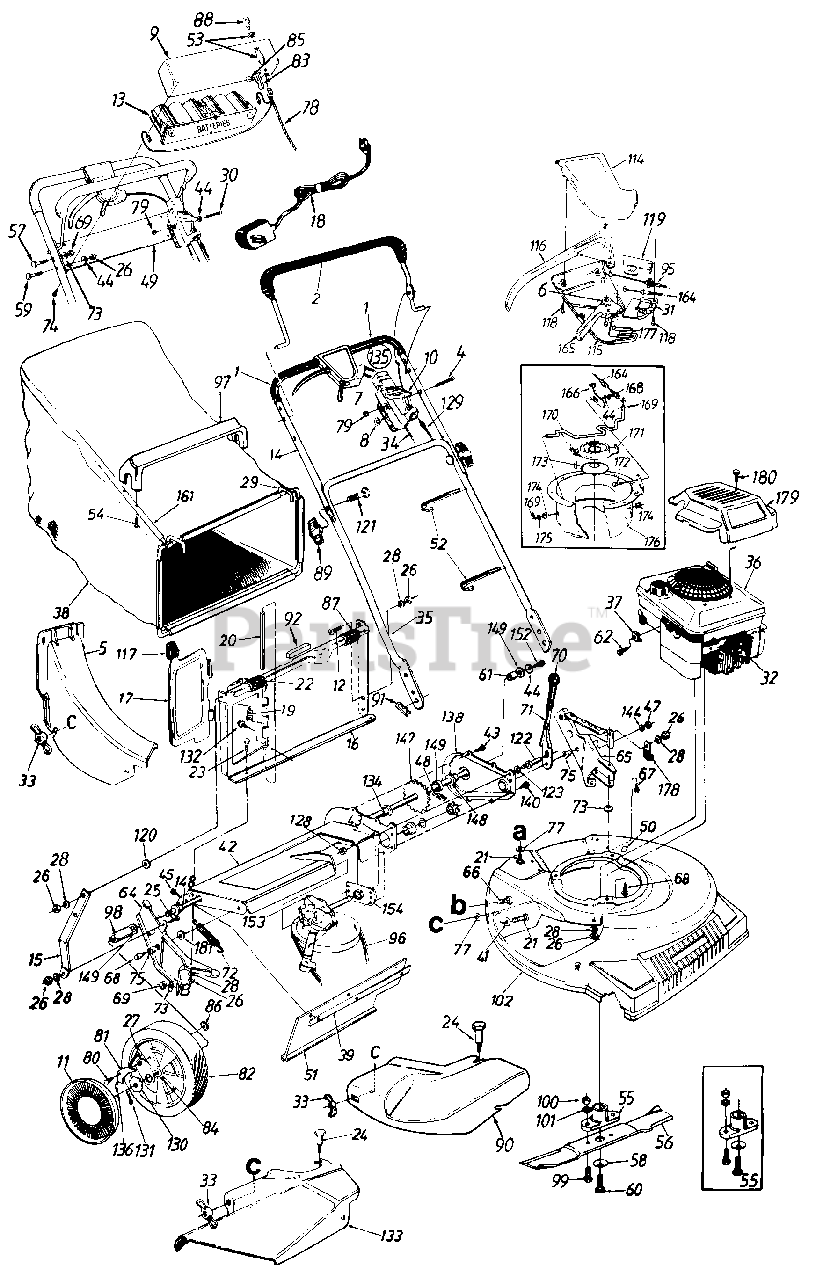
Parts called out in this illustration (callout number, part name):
1	Grip (2 Req'd.)
2	Control Handle
4	Oval C-Sunk Scr.
5	Rear Discharge Chute Ass'y.
6	3 Tooth Rack Gear Insert
7	Throttle Body
8	Spr. Wash. .66" I.D.
9	Battery Tray
10	Throttle Lever
11	Hub Cap (Beige)
12	Truss Mach. Scr. 1/4-20 x .62" Lg.
13	Battery Pack-12 Volt
18	Battery Charger
19	Torsion Spring
20	Pivot Pin
21	Carriage Bolt 1/4-20 x .62"
22	Truss Mach. Scr. 1/4-20 x .75" Lg.
23	Hex Bolt 1/4-20 x .5" Lg.
24	Shoulder Bolt Special
25	Hex Bolt 1/4-20 x .62" Lg.
26	Hex Nut 1/4-20 Thd.
27	Pawl Plate
28	L-Wash. 1/4" I.D.
30	Hex Bolt 1/4-20 x 2" Lg.
31	S.P. Control Cover
32	Spark Plug Insulator
33	Wing Nut
34	Throttle Cable 61"
36	Engine
37	Casing Clamp
38	Grass Bag
39	Retaining Strip
41	Fl-Wash. .344" I.D. x .62"
44	Bell-Wash. 1/4" I.D.
45	Hex AB-Tap Scr. 1/4 x .62"
47	Hex Patch L-Nut 3/8-24 Thd.
48	#48 Chain .500" Pitch x 30 Links
51	Rear Flap 3.75" x 17.30" Lg.
52	Cable Tie
53	Ignition Switch
54	Hex AB-Tap Scr. #12 x 1.25" Lg.
55	Blade Adapter Kit
56	21" Mulching Blade
57	Curved Carr. Bolt 5/16-18 x 1.38" Lg.
58	Bell-Wash. .46" I.D.
59	Carr. Bolt 1/4-20 x 1.25" Lg.
60	Hex Bolt 7/16-20 x 1.5"
61	Spacer.513" I.D.
62	Hex Wash. Hd. Scr. #10-32 x .62" Lg.
64	R.H. Handle Wheel Brkt. Ass'y.
65	L.H. Handle Wheel Brkt. Ass'y.
66	Carriage Bolt 5/16-18 x .62"
67	Hex B-Tap Scr. 5/16-18
68	Hex TT-Tap Scr. 3/8-16
69	Hex Nut 5/16-18 Thd.
71	Height Adj. Lever
72	Extension Spring 3.80" Lg.
73	Bell-Wash. 5/16" I.D.
74	Truss Mach. Tap Scr. 1" Lg.
75	Shld. Spacer .5" Dia.
77	Bolt Retainer 1/4 x .50" O.D.
78	Wire Harness
79	Hex L-Nut 1/4-20 Thd.
80	Shld. Scr. .342" Dia. x .268
81	Pawl
82	Wheel Ass'y. Comp. (Beige)
83	Plug
84	Sleeve Bearing 1/2" I.D.
85	Fuse Holder
86	Flat Nut 1/4-20 Thd.
87	Panel Clip
88	Ignition Key
89	Hand Knob
90	Mulching Plug
91	Hairpin Clip
92	Foam Strip 1/4" x 1" Lg.
95	S.P. Cable-50" Lg.
96	"V"-Belt
97	Bag Handle
98	Sleeve .526" I.D.
99	Hex Bolt 3/8-24 x 1.0" Lg.
100	Hex Nut 3/8-24 Thd.
101	L-Wash. 3/8" I.D.
115	Self-Propelled Control Cover
116	Control Lever
117	Door Grip
118	Fl-"C"-Sunk Hd. Tap Scr. #10 x .75" Lg.
119	6-Speed Rack Cable Brkt.
120	Fl-Wash. .285" I.D. x 1.25" O.D.
121	Curved Hd. Bolt 5/16-18 x 2" Lg.
122	Shld. Pin 1.43" Lg.
123	L-Wash. 3/8" I.D.
128	Hex Jam Nut 3/8-24 Thd.
129	Control Cable-44"
130	Ratchet Wheel 1.62" O.D.
131	Cotter Pin 1/8" Dia. x 1"
132	Hex B-Tap Scr. #10 x .38" Lg.
133	Side Chute Deflector Ass'y.
134	Hex Flange Bearing
135	Throttle Box Comp.
136	Spring-Nylon
144	Fl-Wash. .385" I.D. x .87"
147	Rear Shaft Ass'y. 21.94" Lg.
148	Hex Flange Brg. .506" I.D.
149	Fl-Wash. .531" I.D. x .930"
152	Hex Bolt 1/4-20 x .62" Lg. (Grade 5)
153	Transmission Comp.
164	Spd. Control Cable-50" Lg.
165	6-Spd. Shift Lever
169	Cot-Pin 3/32" Dia. x .75" Lg.
170	Shift Rod
171	Movable Pulley Half Ass'y.
172	Carr. Bolt 1/4-20 x .5" Lg.
173	Splined Pulley Half
174	Flanged Bushing
175	Fl-Wash. .328" I.D. x .68" O.D.
176	Housing Ass'y.
177	Shift Lever Spring
179	Engine Cover (Black)
180	Screw #10 x 1.25" Lg.
181	Fl-Wash. .383" I.D. x 1" O.D.
16862A-0637	PANEL ASSEMBLY-CATCHER - POWDER BLACK (0637)
16862A-0638	PANEL ASSEMBLY-CATCHER - MTD/TROY-BILT RED (0638)
16862A-0648	PANEL ASSEMBLY-CATCHER - TECH GRAY (0648)
16862A-0662	PANEL ASSEMBLY-CATCHER - OYSTER GRAY (0662)
16862A-0665	PANEL ASSEMBLY-CATCHER - YARDMAN GREEN (0665)
17051B-0638	DECK-ASSEMBLY-21IN(MTD RED) - MTD/TROY-BILT RED (0638)
17051B-0662	DECK-ASSEMBLY-21IN(OYSTER GRAY) - OYSTER GRAY (0662)
17053A-0483	COVER-CHAIN - CHARCOAL GRAY (0483)
17053A-0637	COVER-CHAIN (POWDER BLACK) - POWDER BLACK (0637)
17053A-0638	COVER-CHAIN - MTD/TROY-BILT RED (0638)
17053A-0650	COVER-CHAIN - RED METALLIC (0650)
17053A-0662	COVER-CHAIN - OYSTER GRAY (0662)
17053A-0665	COVER-CHAIN - YARDMAN GREEN (0665)
17053A-0674	COVER-CHAIN - YARDMAN YELLOW (0674)
17055B-0498	AXLE ASSEMBLY-CHAIN (CUB YELLOW) - OLD CUB YELLOW (0498)
17055B-0629	AXLE ASSEMBLY-CHAIN SILVER FLAK - SILVER FLAKE (0629)
17055B-0637	AXLE ASSY-CHAIN - POWDER BLACK (0637)
17055B-0638	AXLE ASSY-CHAIN - MTD/TROY-BILT RED (0638)
17055B-0648	AXLE ASSEMBLY-CHAIN (TECH GRAY) - TECH GRAY (0648)
17055B-0650	AXLE ASSEMBLY-CHAIN RED METALL - RED METALLIC (0650)
17055B-0662	AXLE ASSEMBLY-CHAIN (OYSTER GRAY) - OYSTER GRAY (0662)
17055B-0667	AXLE ASSEMBLY-CHAIN MIDNIGHT BL - MIDNIGHT BLUE (0667)
17055B-0691	AXLE ASSEMBLY-CHAIN (BLACK JACK) - BLACK JACK (0691)
